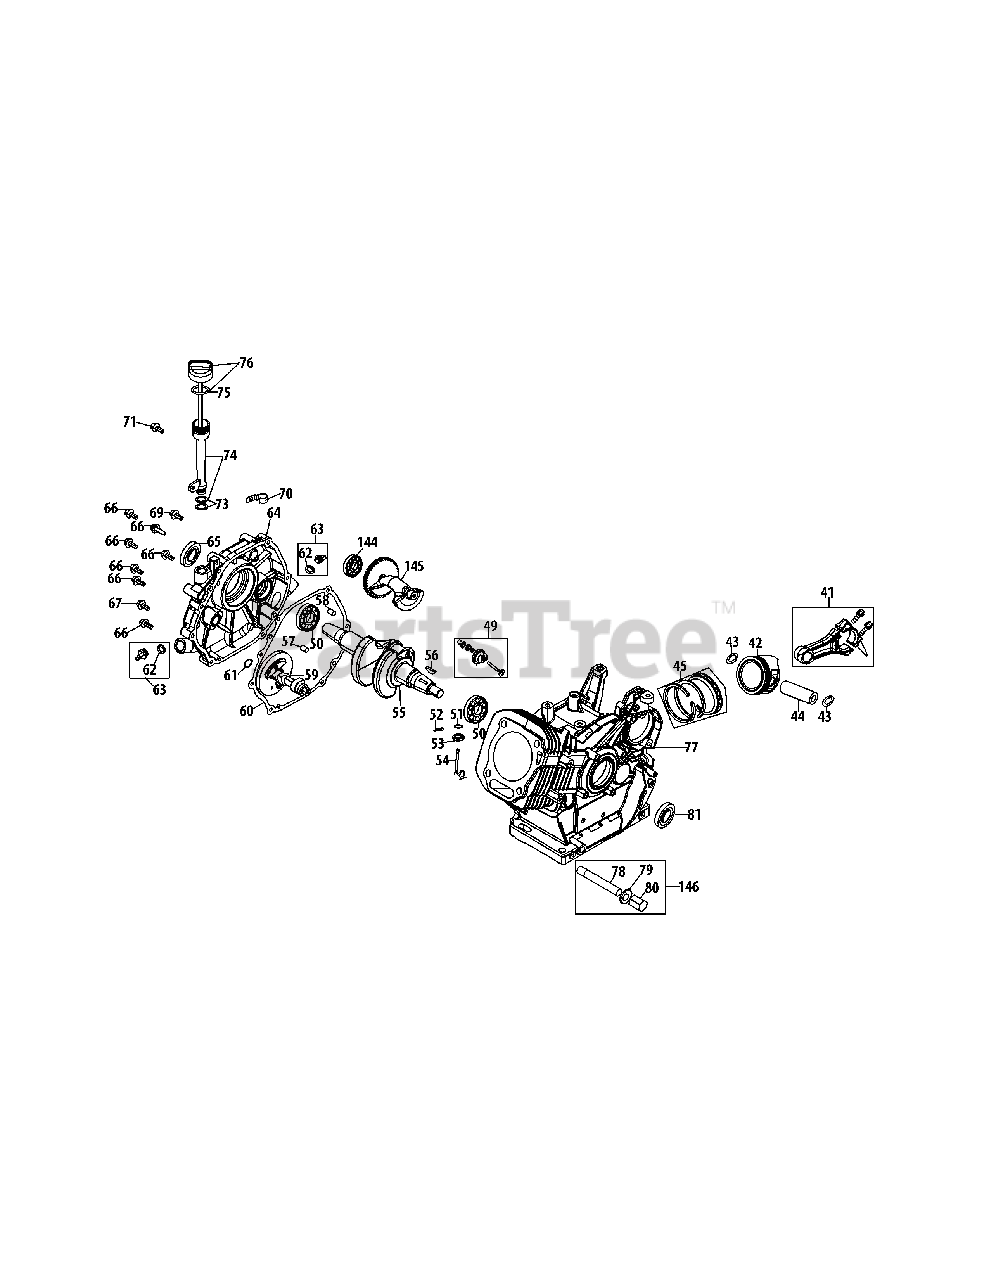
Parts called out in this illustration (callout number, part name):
41	Connecting Rod Assembly
43	Piston Pin Snap Ring
44	Piston Pin
45	Piston Ring Set
49	Governor Gear/Shaft Assembly
50	Radial Ball Bearing, 6202-P6
51	Washer 8×20×0.8
52	Cotter Pin
53	Governor Seal
54	Governor Arm Shaft
55	Crankshaft Kit
56	Woodruff Key
57	Dowel Pin 9×12
58	Dowel Pin 7×14
59	Camshaft Assy.
60	Crankcase Cover Gasket
61	Washer 16×24×0.5
62	O-Ring 16×3
63	Oil Filler Plug Assembly
64	Crankcase Cover Kit
65	Oil Seal, 30×46×8
66	Bolt M8×38
67	Bolt M8×45
68	Bolt M8×35
69	Bolt M6×16
70	Dipstick Clamp
71	Bolt M6×8
73	Oil Fill Tube O-Ring
74	Oil Fill Tube Assembly
75	Dipstick O-Ring
76	Dipstick Assembly
77	Crankcase Kit
78	Oil Drain Pipe Assy.
79	Washer 10×16×1.5
80	Oil Drain Plug
81	Oil Seal 35×52×7
144	Bearing, 6207-P6
145	Balance Shaft Assembly
146	Oil Drain Assembly
